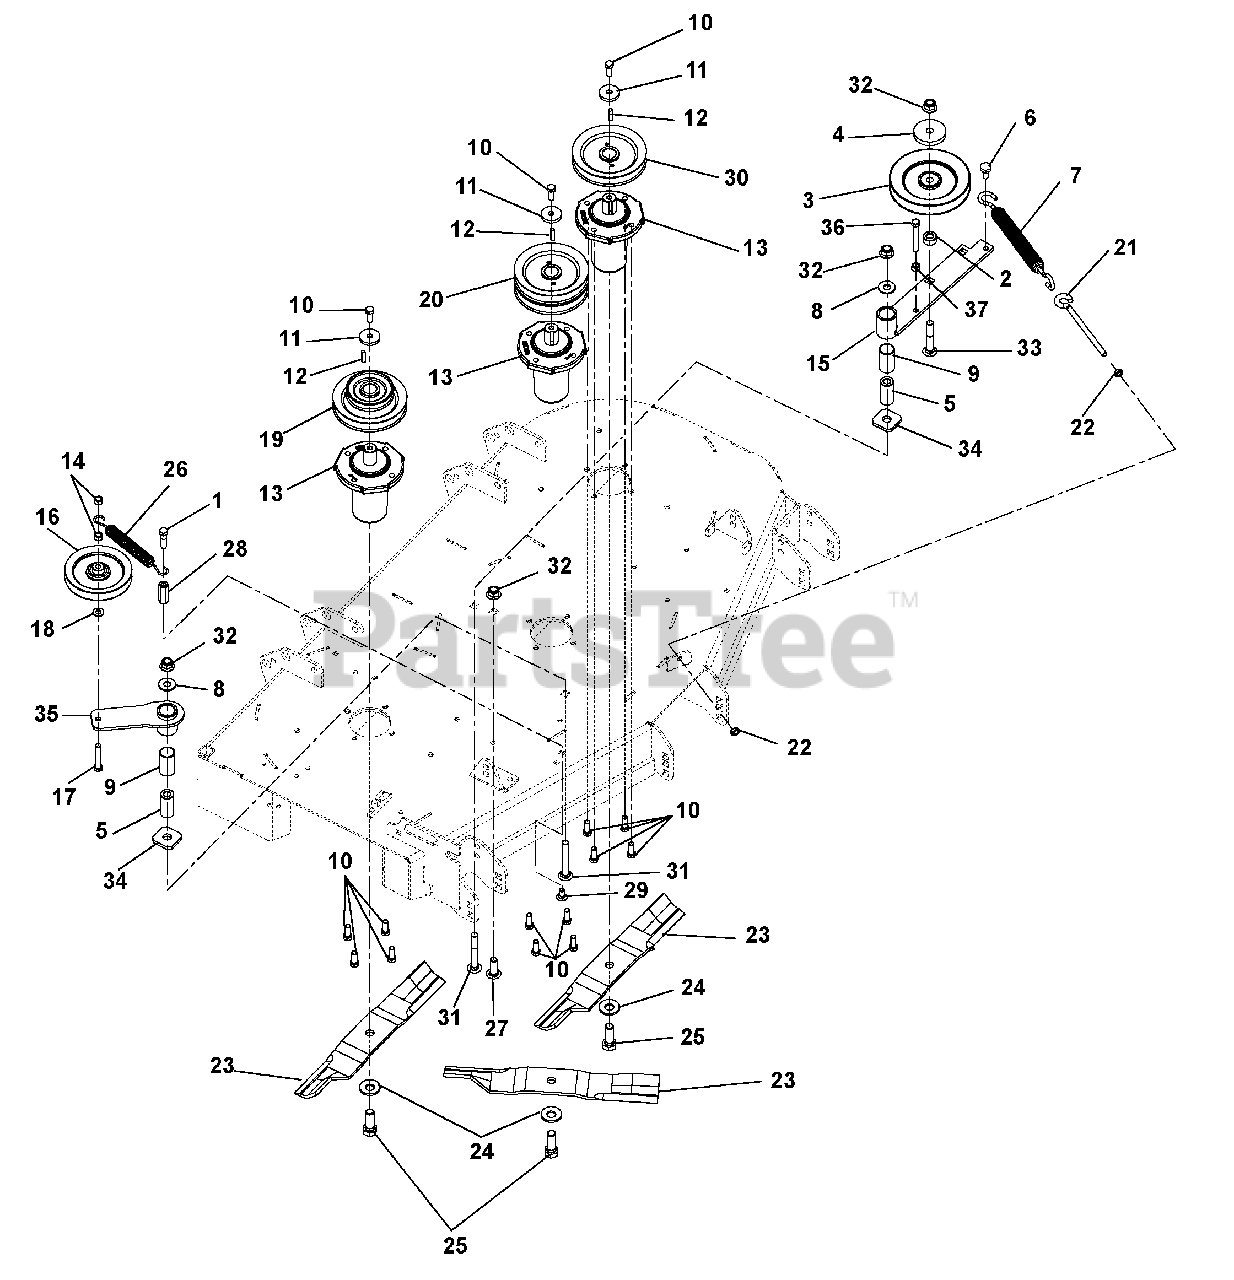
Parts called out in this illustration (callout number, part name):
1	Bolt, Hex .38-16 x 1.50 Grade 5
2	Bushing, Spacer .502 x .997 x .50
3	Pulley, V 6.0 x .500 ID Single Bearing
4	Cap, Idler Bearing Sealing
5	Bushing, Spacer .505/.500 x .999/.996 x 2.05/2.03
6	Bolt, Shoulder EP .38-16 x .30 Hex
7	Spring, Extension (Deck Idler)
8	Washer, Flat Steel .531x 1.250 x.100
9	Bushing, 1.00 x 1.125 x 1.936
10	Bolt, Hex .38-16 x 1.00
11	Washer, Flat Steel .406 x 1.50 x .245
12	Key, Square .25 x .25 x 1 RC 40-50
13	Spindle Assembly
14	Nut, Locking-Center .38-16
15	Weldment, Idler Arm
16	Sheave, .38" ID x 5" OD
17	Bolt, Hex .38-16 x 2.25
18	Washer, Flat Steel .406 x .812 x .065
19	Sheave, 44-48 Bagger Drive (062)
20	Sheave, Double 1.0" ID x 5.50" OD (062)
21	Bolt, .38-16 x 5.50 .62 Diameter Eye
22	Nut, Hex, Jam .375-16
23	Blade, 16.19" Mower (062)
24	Washer, Bellville .63 x 1.625 x.14
25	Bolt, Hex .62-18 x 1.75 Grade 8
26	Spring, Extension
27	Bolt, Round Head Square Neck .50-13 x 1.5, Full Thread, Grade 5
28	Nut, Coupling .375-16 x 1.75
29	Bolt, Round Head Square Neck .38-16 x 1.00
30	Sheave, Single 1.0" ID x 5.50" OD (062)
31	Bolt, Round Head Square Neck .50-13 x 3.50
32	Nut, .50-13 Nyloc Flange
33	Bolt, Round Head Square Neck .50-13 x 3.00 Grade 5
34	Washer, Flat .640 x 1.75 x .250
35	Weldment, Idler Arm
36	Bolt, Hex .38-16 x 2.75 Grade 5
37	Nut, Hex .38-16
